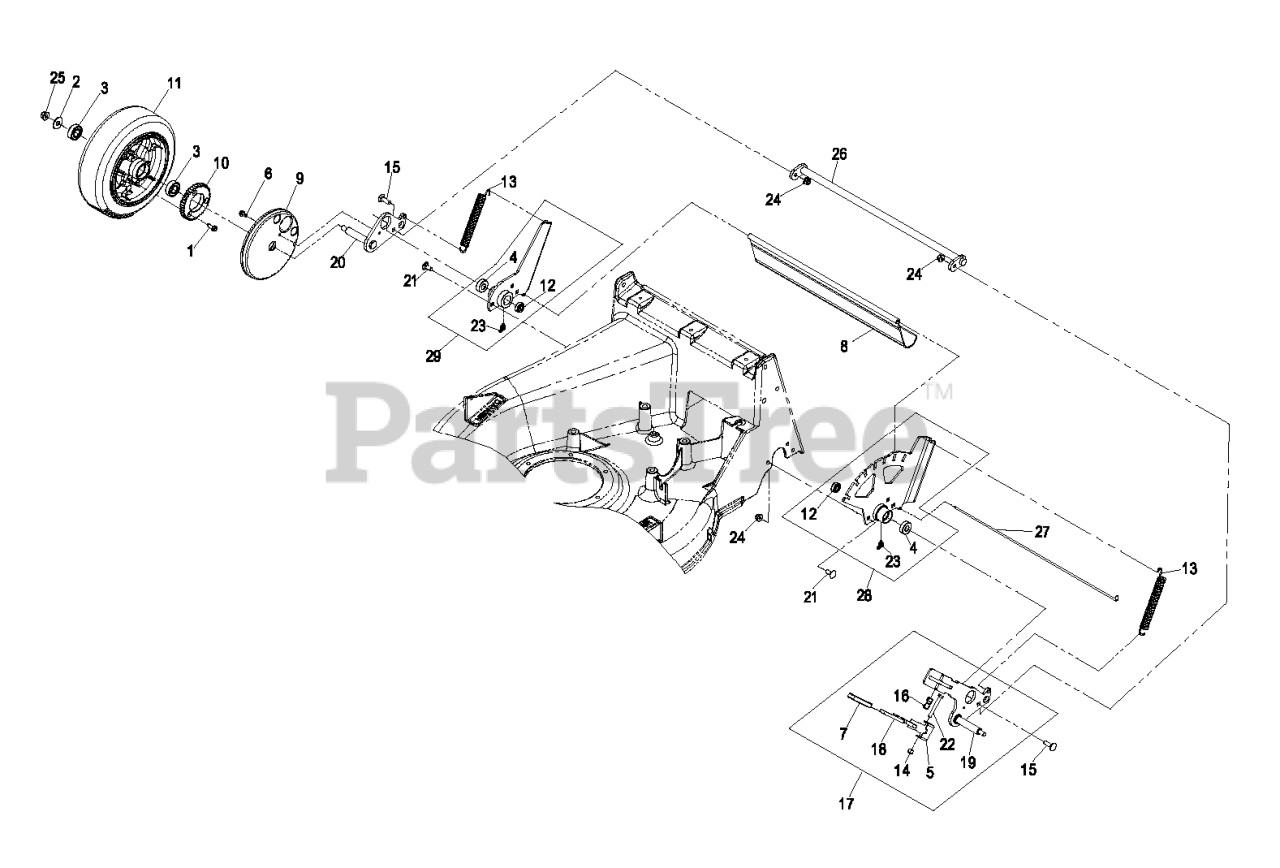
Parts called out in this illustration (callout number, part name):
3	BEARING-BALL
4	BEARING-AXLE, REAR
5	BRACKET-PIVOT, LIFT
7	COVER-HANDLE
9	COVER-GEAR
10	GEAR-DRIVEN
11	ASM,10" TIRE AND WHEEL
12	SEAL-AXLE
13	SPRING-ASSIST, LIFT
14	NUT-LOCK, NI
15	BOLT-CARR
16	SPRING-LATCH
17	ASM,REAR ADJUSTER
18	LEVER-LIFT
19	ARM-AXLE, LH
20	ARM-AXLE, RH
21	BOLT-CARR
22	SCREW-HH
23	FITTING-GREASE
24	NUT-HF, NI
25	NUT-HF, NI
26	ROD-TORQUE
27	ROD-SHIELD
28	LH BEARING SUPPORT ASM
29	RH BEARING SUPPORT ASM
